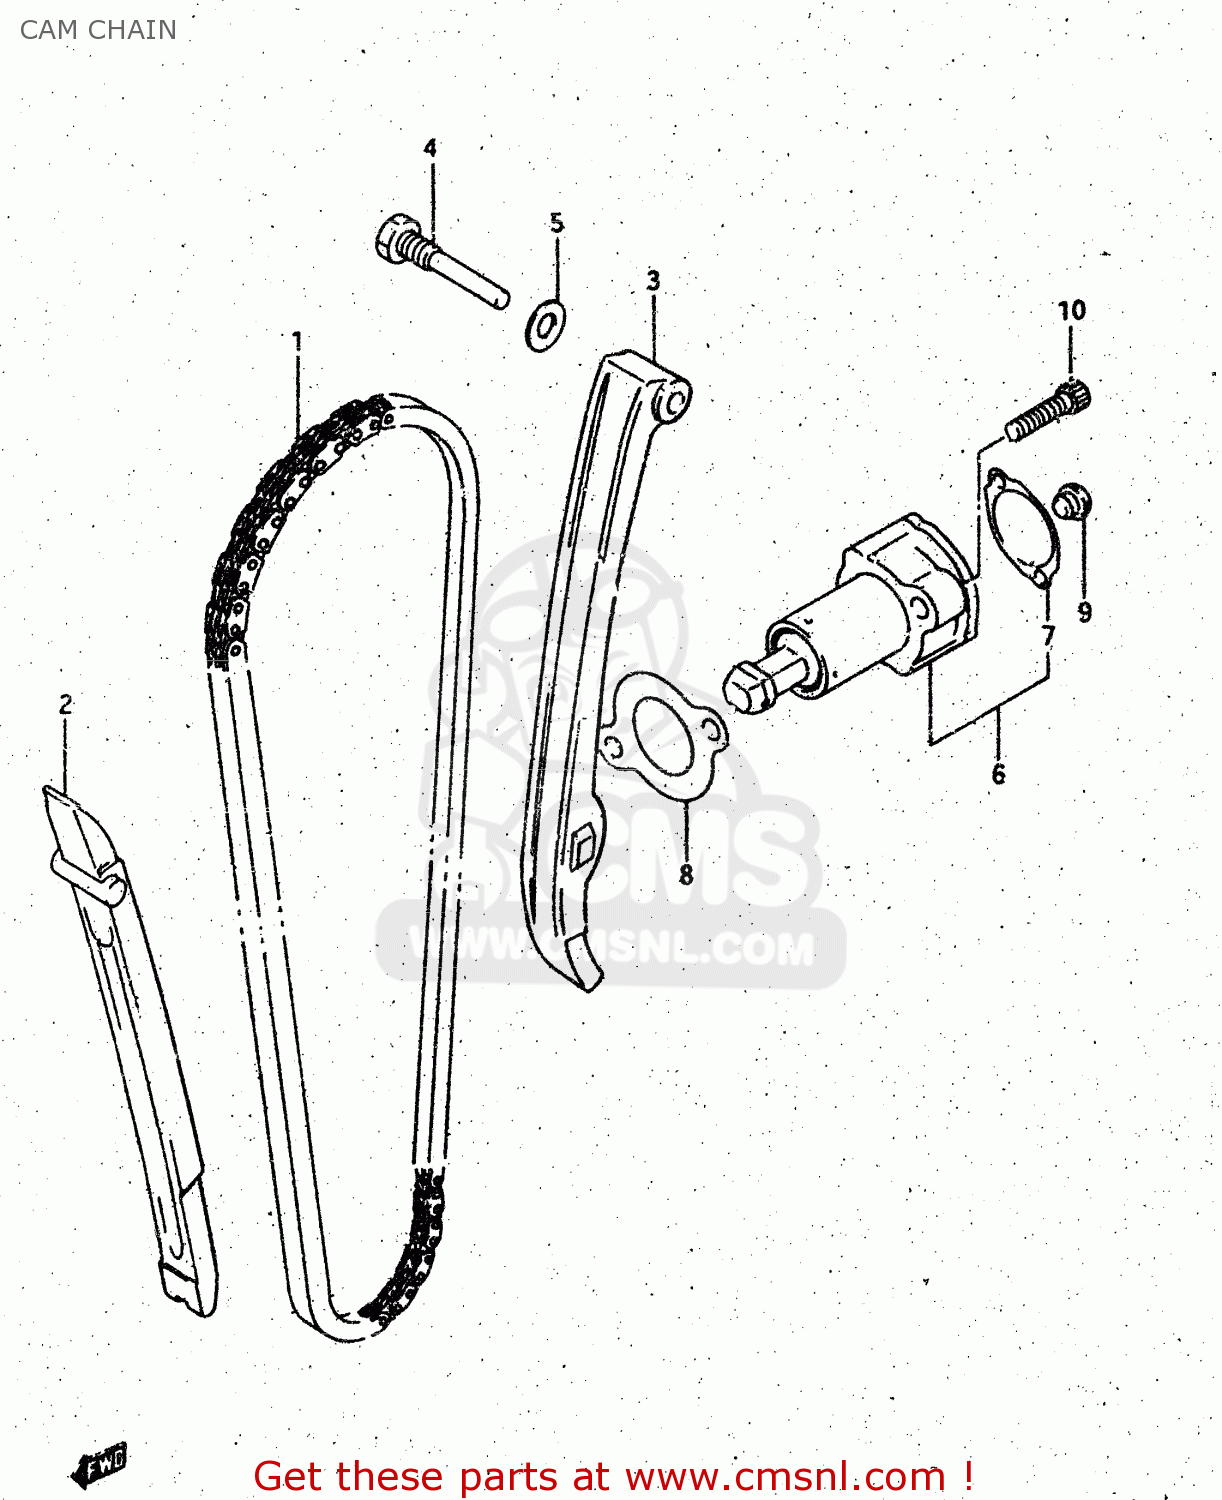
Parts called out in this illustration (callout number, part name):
1	CHAIN,CAMSHAFT DRIVE
2	GUIDE,CAM CHAIN
3	TENSIONER,CAM CHAIN
4	BOLT,CAM CHAIN TENSIONER
5	GASKET 8.2X14X1 (NAS)
6	ADJUSTER ASSEMBLY,TENSIONER
7	GASKET,ADJUSTER CAP (MCA)
8	GASKET,TENSIONER ADJUSTER (NAS)
9	PLUG,ADJUSTER
10	BOLT
